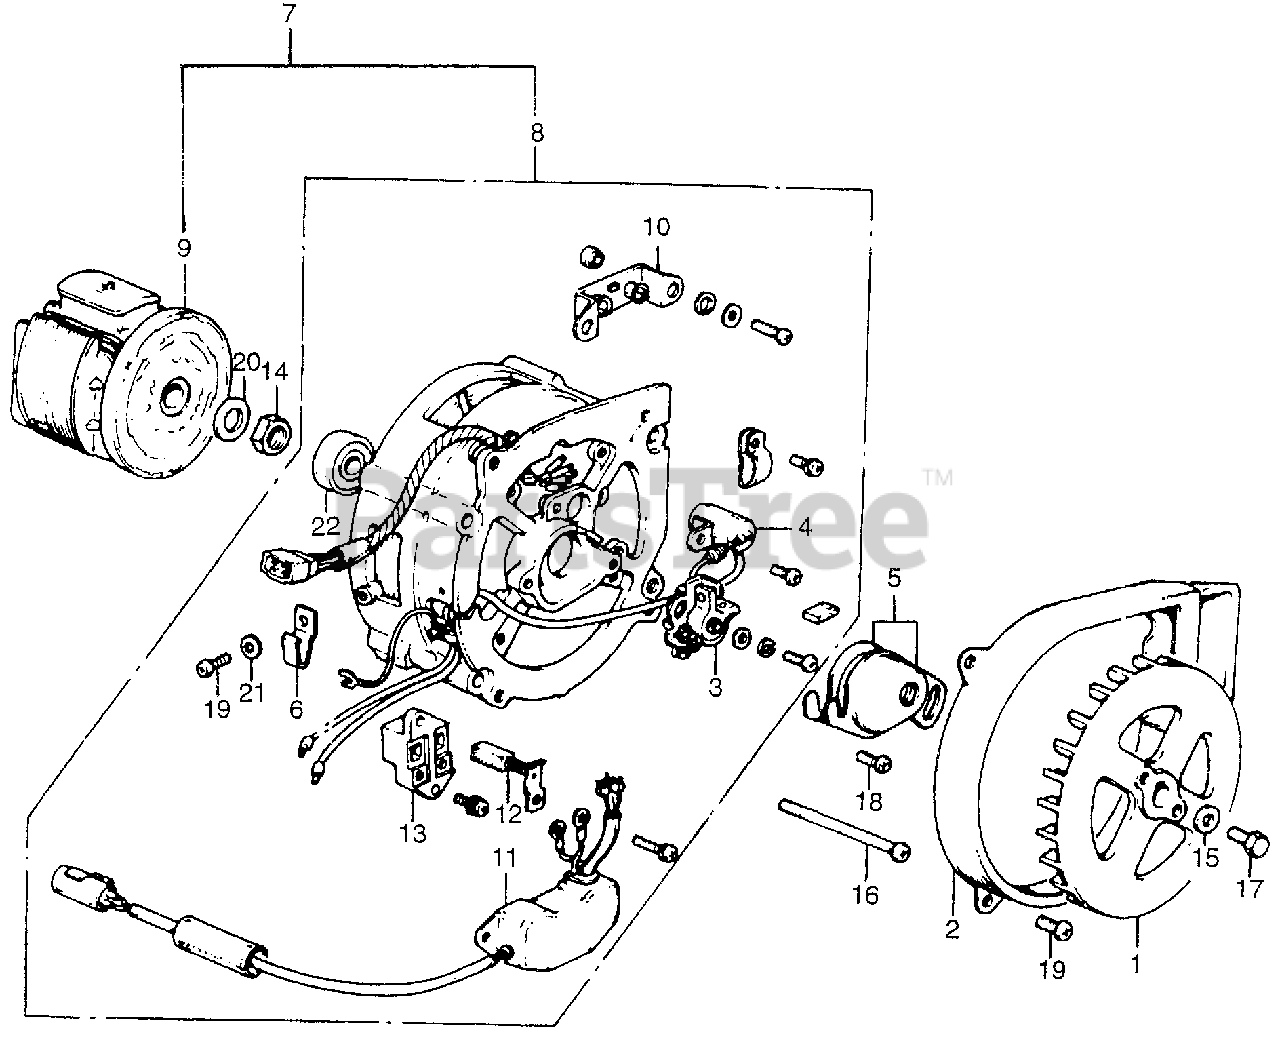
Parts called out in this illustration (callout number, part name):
1	FAN, ALTERNATOR COOLING (NOT AVAILABLE)
2	COVER, ALTERNATOR FAN
3	POINTS ASSY. (NOT AVAILABLE)
4	CONDENSER ASSY., IGNITION
5	COVER ASSY., POINTS (NOT AVAILABLE)
6	CLAMP, WIRE
7	ALTERNATOR ASSY.
8	STATOR ASSY., ALTERNATOR
10	DIODE ASSY., D.C. OUT
11	REGULATOR, AUTOMATIC VOL TAGE (NOT AVAILABLE)
12	BRUSH (NOT AVAILABLE)
13	HOLDER, BRUSH (NOT AVAILABLE)
14	NUT, SPECIAL (14MM)
15	WASHER (6X17)
16	BOLT, ALTERNATOR SET (NOT AVAILABLE)
17	BOLT, HEX. (6X12)
18	SCREW, PAN (4X8)
19	SCREW, PAN (5X10)
20	WASHER, PLAIN (14MM)
21	WASHER, SPRING (5MM)
22	BEARING, RADIAL BALL (6001UU)
